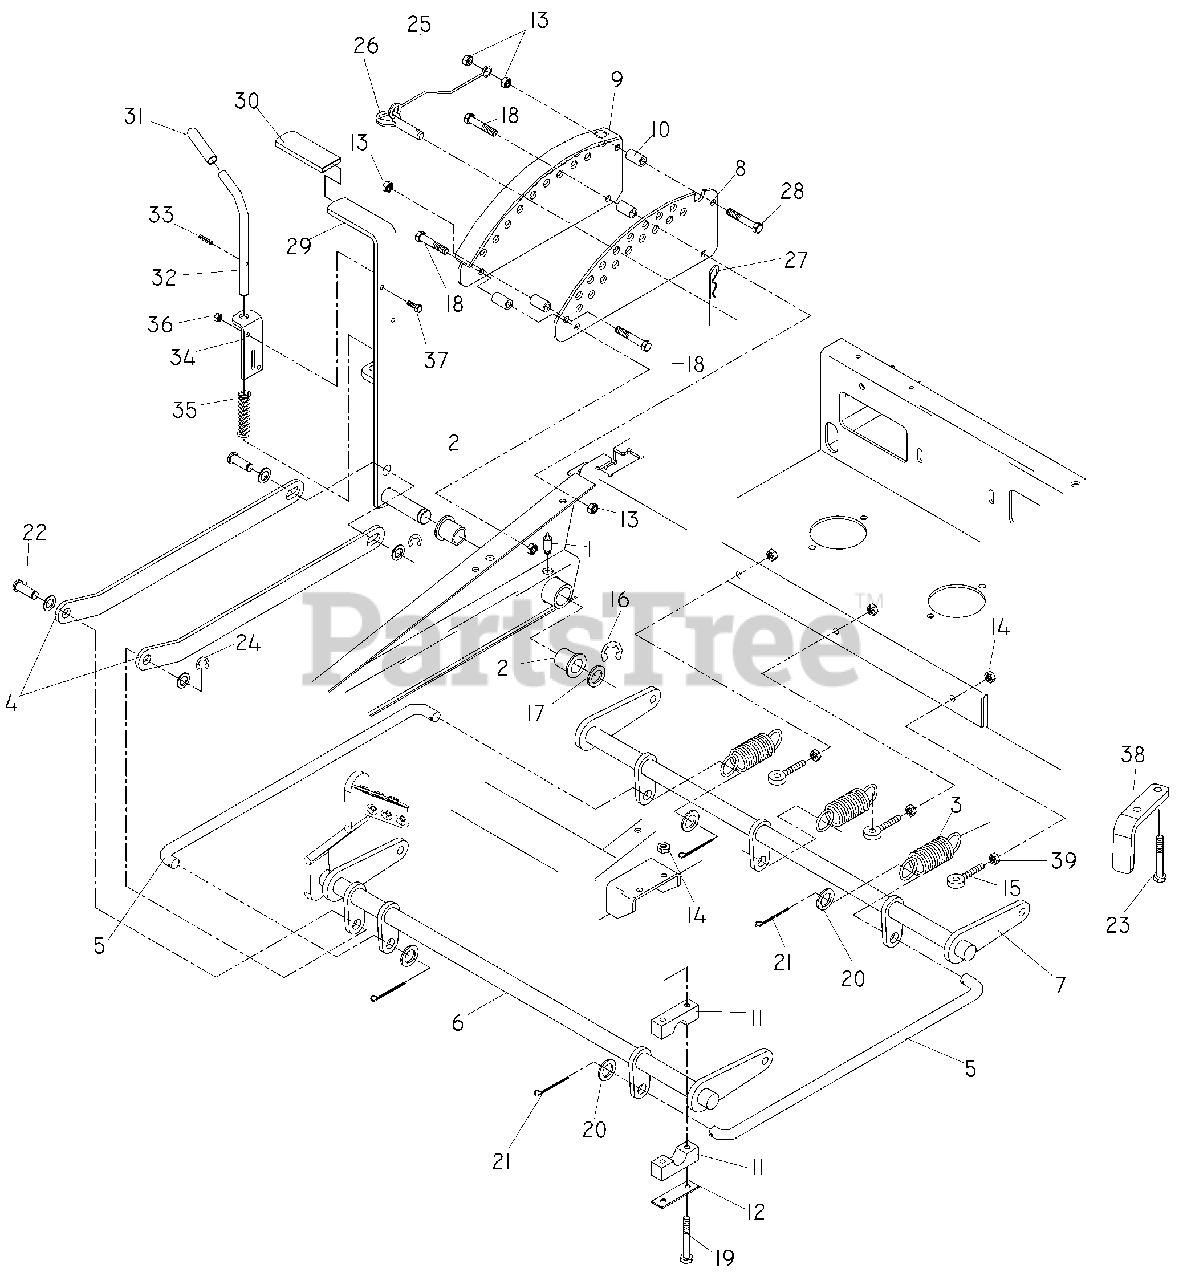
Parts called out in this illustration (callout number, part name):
1	ZERK, LONG
2	BUSHING, FLANGE
3	SPRING, DECK LIFT
4	LINKAGE, LIFT
5	LINK, CONNECTING
6	SHAFT ASSM W/PEDAL, FT
7	SHAFT, REAR LIFT
8	PLATE, ADJUSTMENT
9	PLATE, ADJUSTMENT
10	SPACER, DECK LIFT
11	BLOCKS, PILLOW
12	PLATE, SUPPORT
13	NUT 3/8-16 HEX NYLOC
14	NUT 5/16-18 HEX NYLOC
15	EYEBOLT, 5/16C
16	E-RING, 7/8
17	BUSHING, MACHINE
18	HCS, 3/8C x 2½
19	HCS, 5/16C x 2¾
20	WASHER, 5/8, SAE
21	PIN, COTTER
22	PIN, CLEVIS 5/8
23	BOLT, 3/8-16 x 1, THD FORM
24	E-RING, 5/8
26	PIN, HITCH
27	PIN, HAIR 4
28	HCS, 3/8C x 2¾
29	LEVER, LIFT
30	CUSHION, HANDLE
31	GRIP, VINYL
32	PIN, LOCKING
33	PIN, GROOVED
34	PIN MOUNT, UPPER
35	SPRING, COMPRESSION
36	NUT ¼-20, CENTERLOCK
37	HCS, ¼ - 20 x ¾
39	NUT 5/16-18, WHIZ
